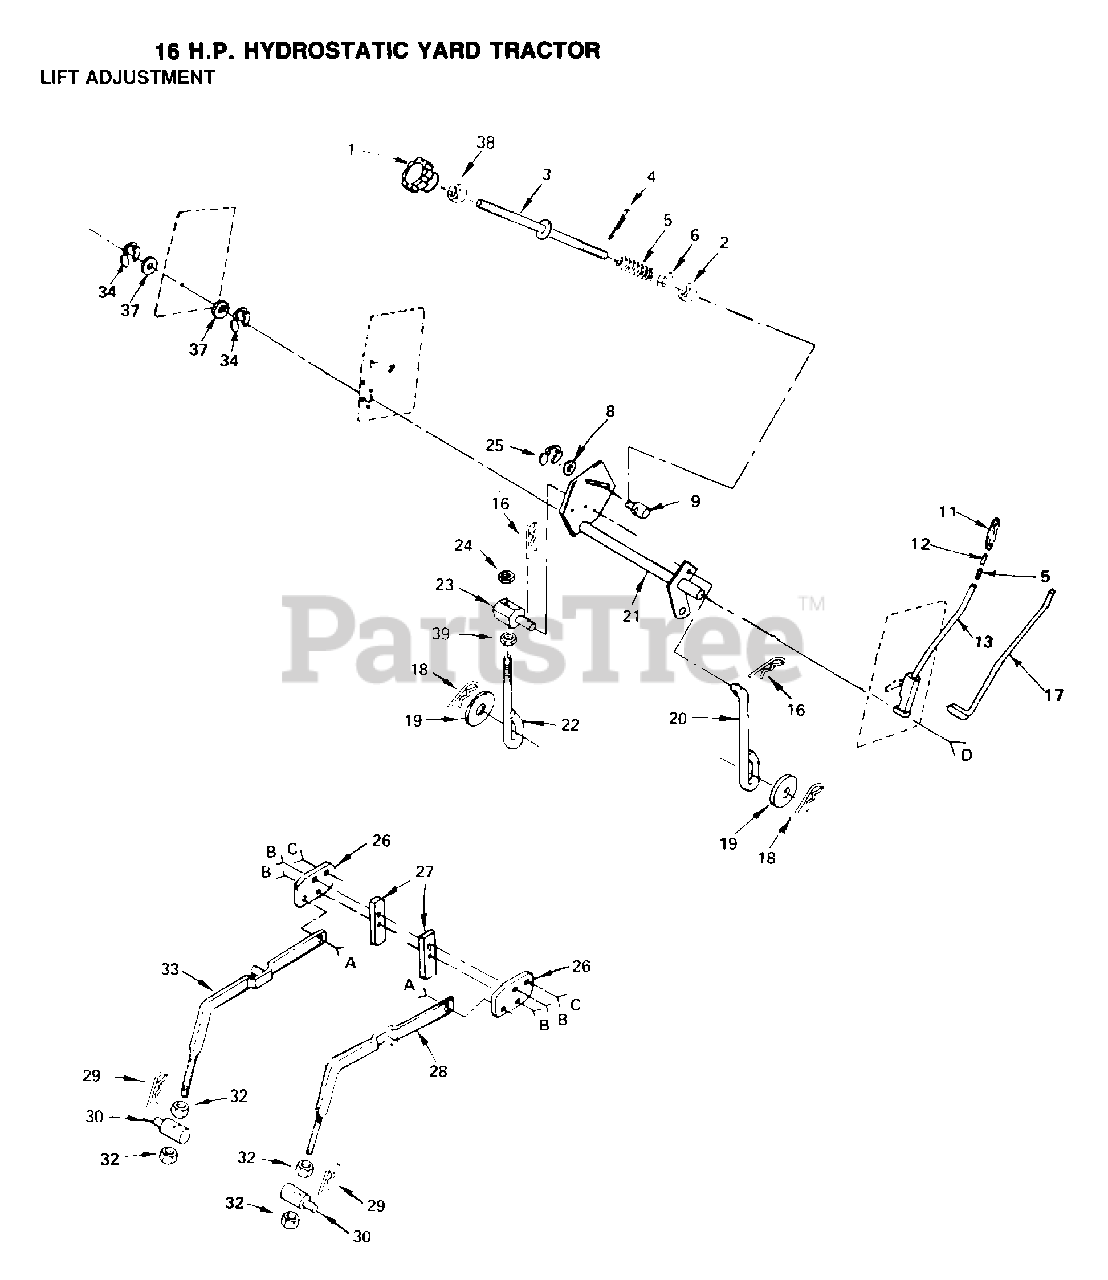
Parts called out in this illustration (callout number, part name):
1	HDLE ADJ LIFT
2	NUT T
3	ROD LIFT LT
5	SPRING T
6	WASHER
8	WASHER
9	TRUNION LT
10	"BOLT, SHOULDER LT"
11	GRIP
14	WASHER T
15	NUT SPECIAL T
17	LEVER ROD LT
18	SPRING.RETAINER
20	LIFT LINK LT
22	PIVOT PIN T
25	KLIP RING
26	"BRACKET, SUSPE T"
27	UPSTOP
29	SPRING H
32	NUT
34	E-RING
36	BOLT
37	WASHER
38	NUT
39	NUT
40	"BOLT,HEX"
